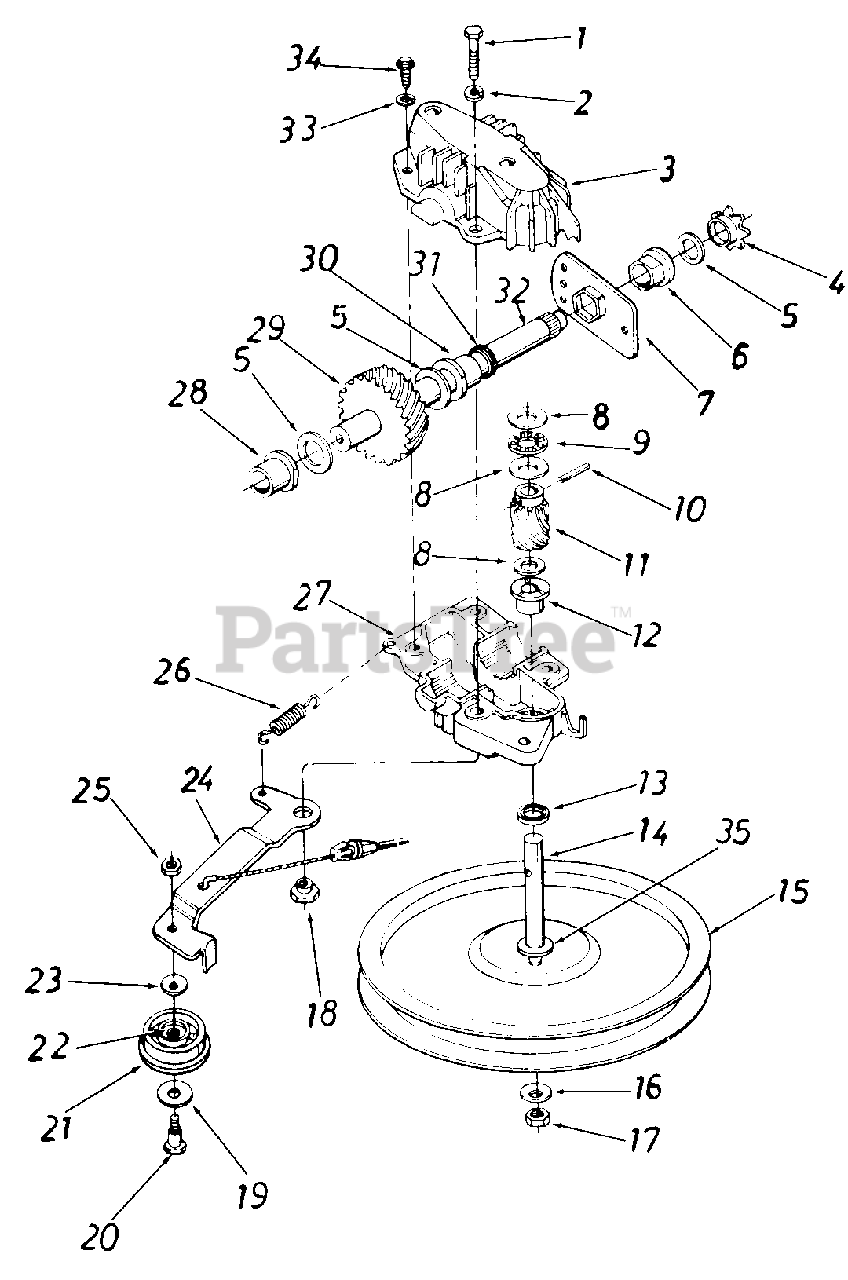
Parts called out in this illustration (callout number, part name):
1	Hex Bolt 1/4-20 x 1.25" Lg.
2	L-Wash. 1/4" I.D.
3	Upper Hsg. Half
4	#48 Sprocket 7 Tooth x 1/2 Pitch
5	Fl-Wash. 518" I.D. x .030
6	Hex Flange Brg. .631" I.D.
7	Hex Bearing Cup
8	Thrust Wash. .382" I.D. x .70" O.D.
9	Thrust Bearing .375" I.D. x .81 2" O.D.
10	Spring Pin Spir. 1/8" x .62" Heavy
11	11 Tooth Helical Gear
12	Flange Bearing
13	Oil Seal
14	Pulley-Transmission Shaft
15	Fl-Pulley 5.06" O.D.
16	Bell-Wash. .265" I.D. x 75"
17	Hex L-Nut 1/4-28 L.H. Thd.
18	Shld. Spacer .375" Dia. x .170
19	Fl-Wash. .390" I.D. x 1.0"
20	Shld. Bolt .375" Dia. x .40"
21	Fl-Idler Plastic 1.50" Dia.
22	Needle Brg. .375" x .31
23	Bell-Wash. .265" I.D. x 75"
24	Idler Brk't. Ass'y.
25	Hex Patch L-Nut 1/4-28 Thd.
26	Extension Spring 1.12" Lg.
27	Lower Hsg. Half
28	Flange Bearing .566 Dia.
29	33 Tooth Helical Gear
30	Flange Bearing .629 Dia.
31	Oil Seal .625 Dia.
32	Gear Sprocket Shaft
33	L-Wash. #10 I.D.
34	Hex B-Tap Scr. #10 x .62"
35	Hex Washer .26" x .88"
